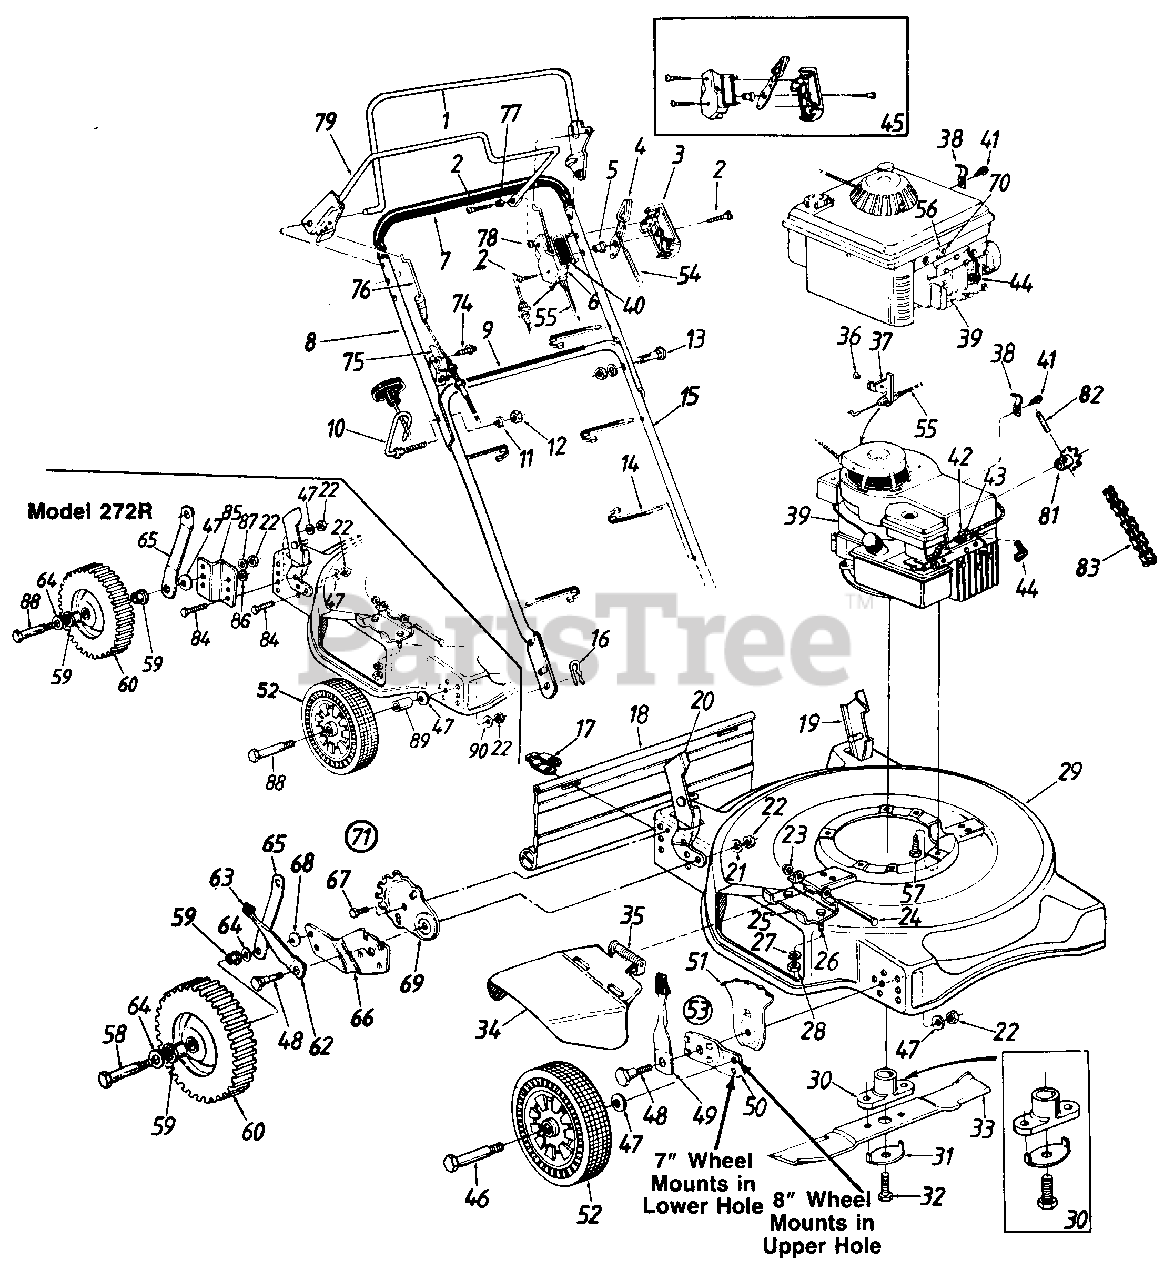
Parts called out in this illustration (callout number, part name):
1	Control Handle Ass'y.
2	Truss Mach. Scr. #12 x 1.5"
3	Control Panel Half
4	Throttle Control Lever
5	Control Disc Pin
6	Clutch Panel Half
8	Upper Handle
9	Instruction Label-Handle
10	Rope Guide Bolt
11	L-Wash. 5/16" I.D.
12	Hex Nut 5/16-18 Thd.
13	Curved Carriage Bolt 5/16-18 x 1.38" Lg.
14	Cable Tie
15	Lower Handle
16	Hairpin Cotter
17	Hinge Clip
18	Rear Flap
19	Handle Bracket Ass'y.-L.H.
20	Handle Bracket Ass'y.-R.H.
21	Bell-Wash. .39" I.D. x 1.38"
22	Hex Nut 3/8-16 Thd.
23	Push Cap 1/4" Rod
24	Pivot Pin
25	Adapter Plate
26	Hex Bolt 1/4-20 x .50" Lg.
27	L-Wash. 1/4" I.D.
28	Hex Nut 1/4-20 Thd.
29	22" Deck Ass'y.
30	Blade Adapter Kit
31	Blade Bell-Wash. .45" I.D.
32	Hex Bolt 3/8-24 x 1.5" Lg.
33	22" Blade
34	Chute Deflector Ass'y.
35	Torsion Spring
36	Pop Rivet
37	Cable Bracket
38	Cable Clamp
39	Engine
40	Throttle Label
41	Hex B-Tap Scr. #10 x .38"
42	Cable Clamp
43	Hex AB-Tap Scr. #8 x 38" Lg.
44	Spark Plug Boot
45	Kit-Control Housing Comp.
46	Front Axle Bolt
47	Bell-Wash. .400" I.D. x .88"
48	Shld. Bolt .50" Dia. x .357"
49	Spring Lever Ass'y. w/Knob
50	Pivot Bar
51	Height Adj. Plate
52	Wheel Ass'y. Comp.
53	Height Adj. Ass'y. Comp.-R.H.
54	Throttle Wire-53"
55	Control Cable-39"
56	Cable Clamp
57	Hex L-Wash. HD. Scr. 3/8-16 x 1.0" Lg.
58	Rear Axle Bolt
59	Fl. Ball Brg. 1/2" I.D.
60	Rear Wheel Ass'y. Comp.
62	Spring Lever
63	Spring Lever Knob
64	Fl-Wash. .531" I.D. x .93"
65	Link 4.58" Lg.
66	Pivot Bar R.H.
67	Hex AB-Tap 1/4-.62" Lg.
68	Bell-Wash. .380" I.D. x .88"
69	Index Plate
70	Hex B-Tap Scr. #10 x .62"
71	Rear Height Adj. Ass'y.-R.H.
74	Hex Wash. AB-Tap Scr. 5/16 x.75" Lg.
75	Cable Brkt.
76	Clutch Cable w/Spring-33"
77	Spacer .23" I.D. x .30" O.D.
78	Spr.-Wash. .206" I.D. x .448
79	S.P. Bail Ass'y.
81	10 Tooth Sprocket Ass'y.
82	Spring Pin Spir. 3/16" Dia. x 1 " Lg.
83	#48 Chain 1/2" Pitch 50 Links (Endless)
84	Hex Bolt 3/8-16 x .75" Lg.
85	Wheel Bracket
86	Fl-Wash. .385" I.D.
87	L-Wash. 3/8" I.D.
88	Shld. Bolt .498" Dia.
89	Spacer .511" I.D.
90	Bell-Wash. .39" I.D.
